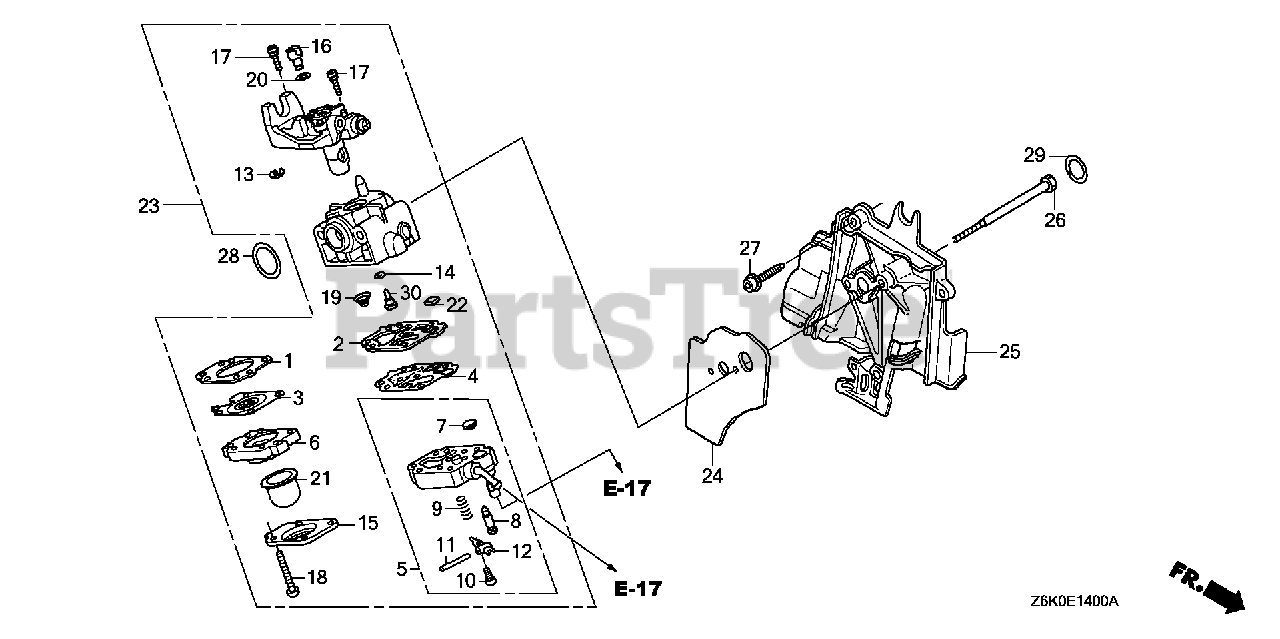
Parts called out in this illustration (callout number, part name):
1	GASKET, METERING DIAPHRAGM
2	GASKET, PUMP
3	DIAPHRAGM ASSY., METERING
4	DIAPHRAGM, PUMP
5	BODY ASSY., PUMP (CARBURETOR NO.)
6	BODY ASSY., AIR PURGE
7	SCREEN, INLET
8	VALVE, INLET NEEDLE
9	SPRING, METERING LEVER
10	SCREW, METERING LEVER PIN
11	PIN, METERING LEVER
12	LEVER, METERING
13	RING, RETAINING
15	COVER, PRIMER PUMP
17	SCREW, THROTTLE COLLAR
18	SCREW, PUMP COVER
19	SPRING, PUMP
21	PUMP, PRIMER
22	FILTER, FUEL INLET
23	CARBURETOR ASSY. (WYB 16C)
23	CARBURETOR ASSY. (WYB 14D)
23	CARBURETOR ASSY. (WYB 36)
23	CARBURETOR ASSY. (WYB 36A)
24	GASKET, CARBURETOR
25	SHROUD
26	BOLT (5X53)
27	BOLT, SOCKET (5X16)
28	O-RING (14.8X2.4)
29	O-RING (12.3X2.4)
30	JET (#35)
30	JET (#36)
